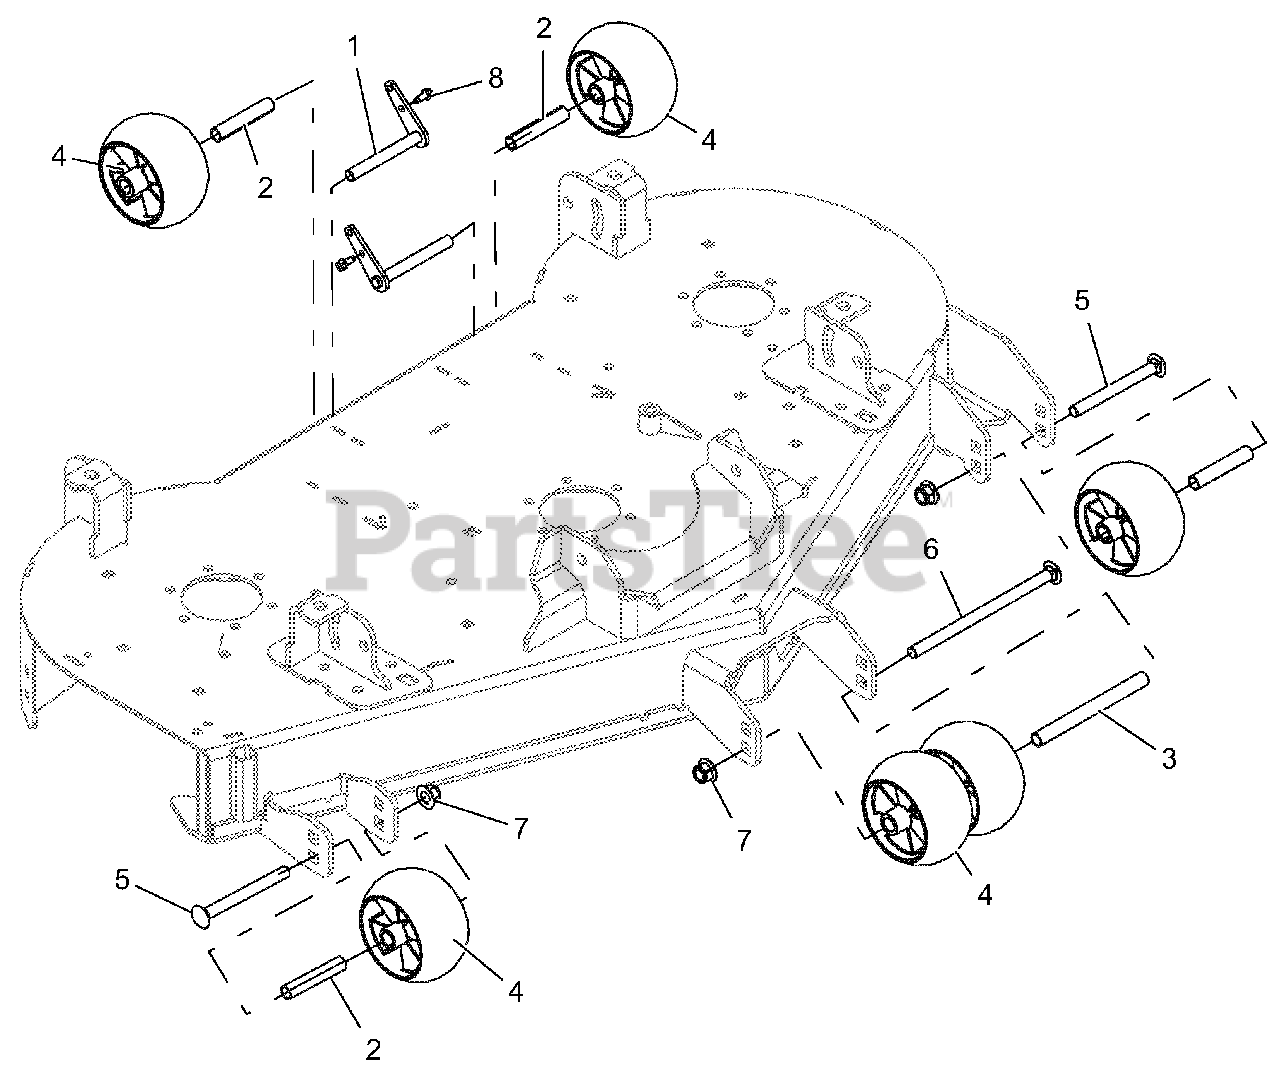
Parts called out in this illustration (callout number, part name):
1	PIVOT, RETAINING WELD
2	SPACER, .510 x .625 x 3.35
3	SPACER, .510 x .625 x 6.70
4	ANTI-SCALP WHEEL - 5 x 3 CTR
5	BLT-RDHDSQNK .50-13 x 5.00 G5 YWZC
6	BLT-RDHDSQNK .50-13 x 8.50 Y
7	NUT-LK-NYL-FLG .50-13 YWZC
8	SCR-TAP .25-20 x .62 HWH TR YWZ
